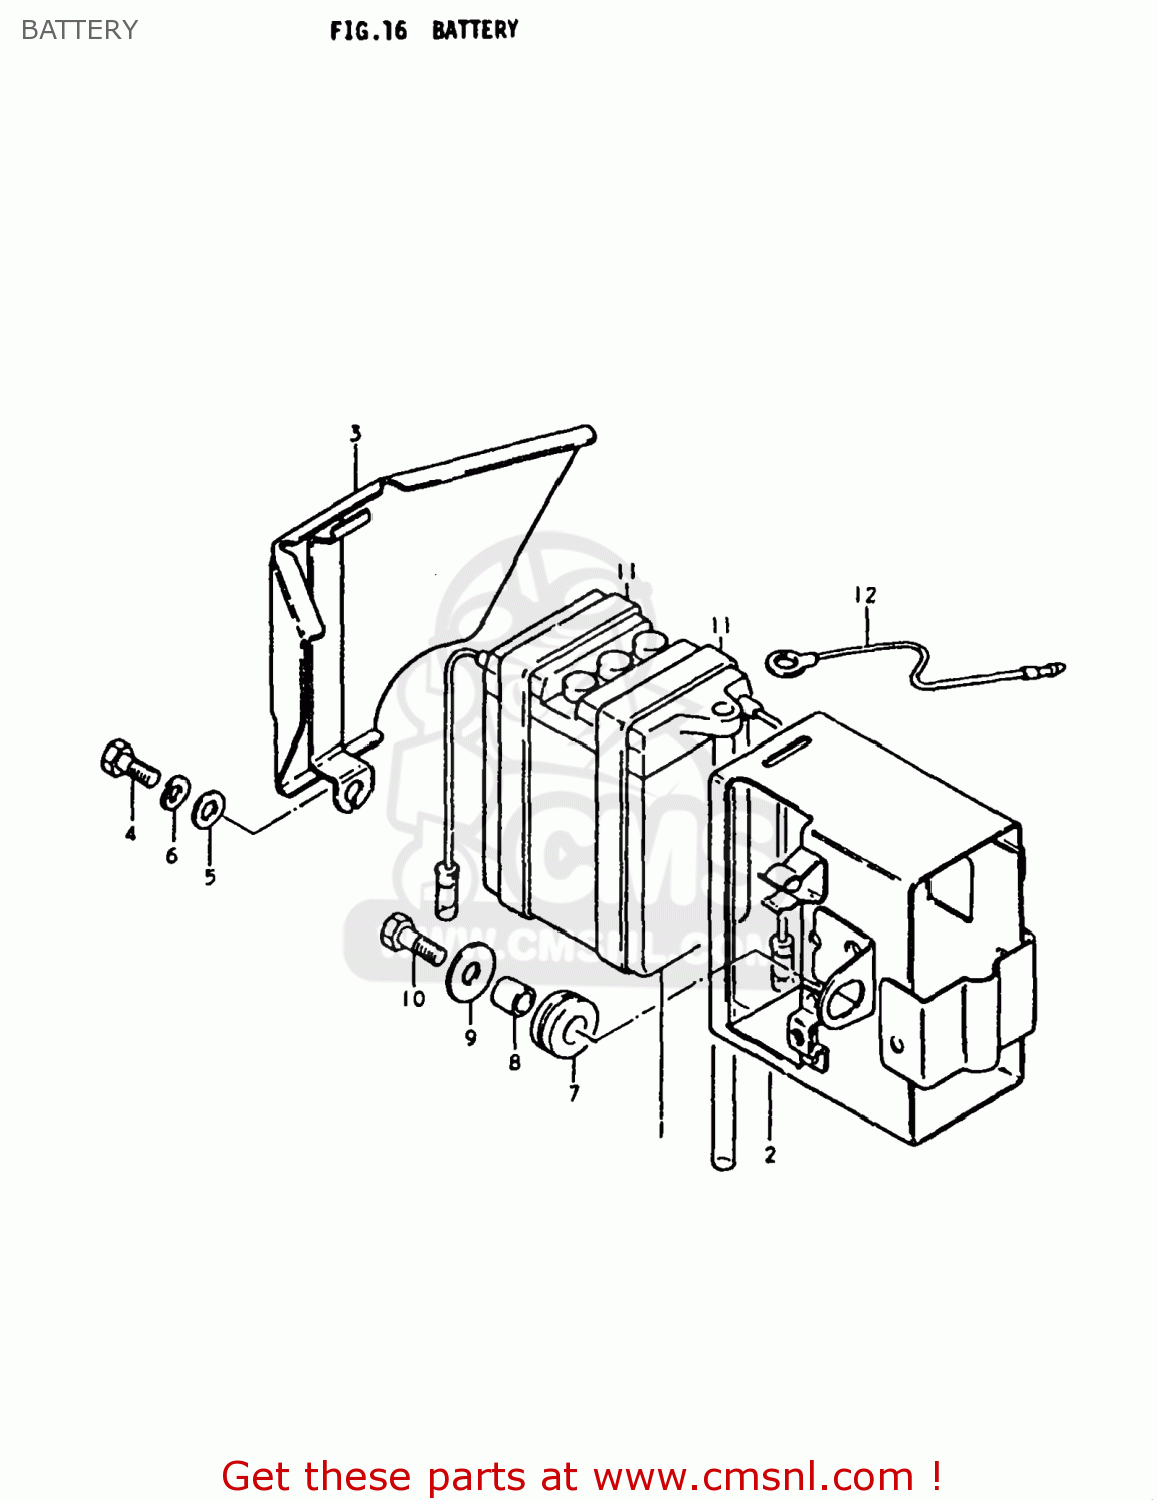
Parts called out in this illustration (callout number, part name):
1	BATTERY(6N4B-2A,6V4.2AH)
2	HOLDER,BATTERY
3	COVER,BATTERY HOLDER
4	SCREW(6X10)
5	WASHER
6	LOCK WASHER
7	CUSHION
8	SPACER (7X9X7)
9	WASHER (6.5X20X1.2)
10	SCREW
11	PROTECTOR,BATTERY
12	LEAD WIRE
